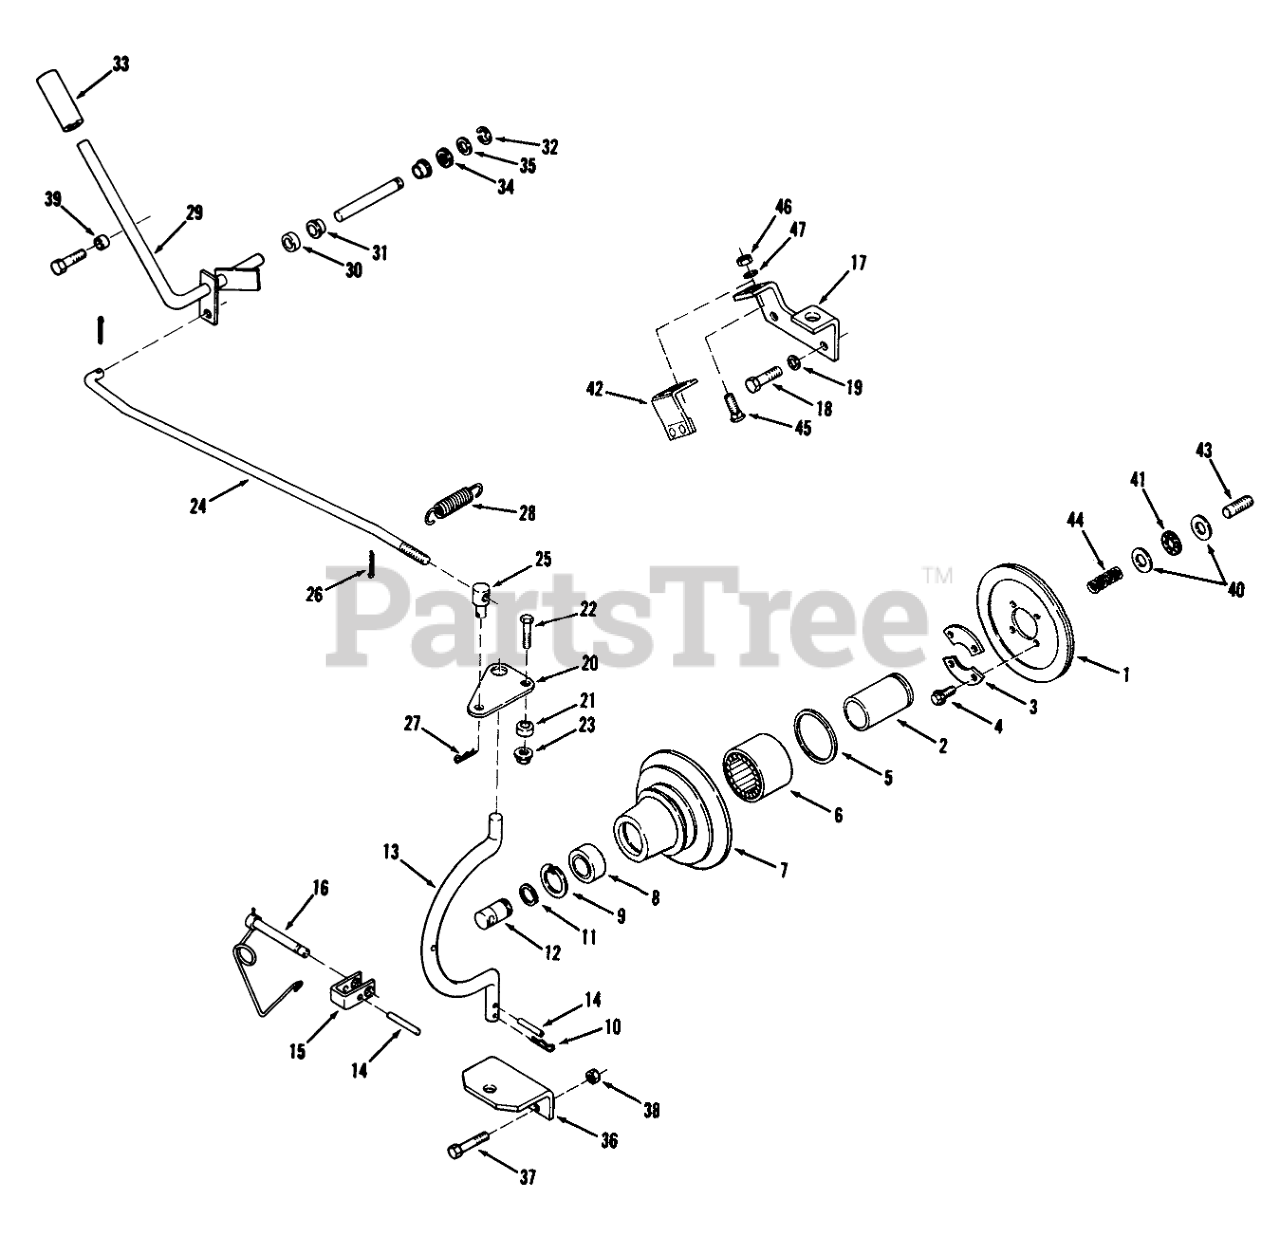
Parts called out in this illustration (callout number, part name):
1	Clutch Plate & Facing
2	RACE-BEARING
2	BEARING RACE
3	RETAINER
4	Screw
5	SEAL-OIL
6	Seal
7	Housing-Clutch
8	Bearing
9	Ring-Snap
10	Hairpin
11	RING-SNAP, EXTERNAL
12	SHAFT-PTO
13	ROD HOUSING (NS)
14	PIN-SPIROL
15	Clevis
16	Pin
17	BRACKET
17	BRACKET-ENGINE B
18	H H C S
18	Bolt
19	LOCKWASHER
20	PLATE R
21	SPACER
22	BOLT
23	LOCKNUT-FLANGE
24	Clutch Rod
25	TRUNNION
26	Pop Rivet
27	Hairpin Cotter
28	Spring
29	Plug, Drain
30	SPACER
31	BUSHING-FLANGED
32	E Ring
33	GRIP
34	Washer
35	SHIM-WASHER
36	Axle
37	Bolt
38	Nut
39	Spacer
40	RACE THRUST
41	THRUST BEARING
42	PTO Plate
43	STUD 7/16
44	SPRING
44	SPRING-COMPRESSION
45	Bolt-Carriage
46	Nut
